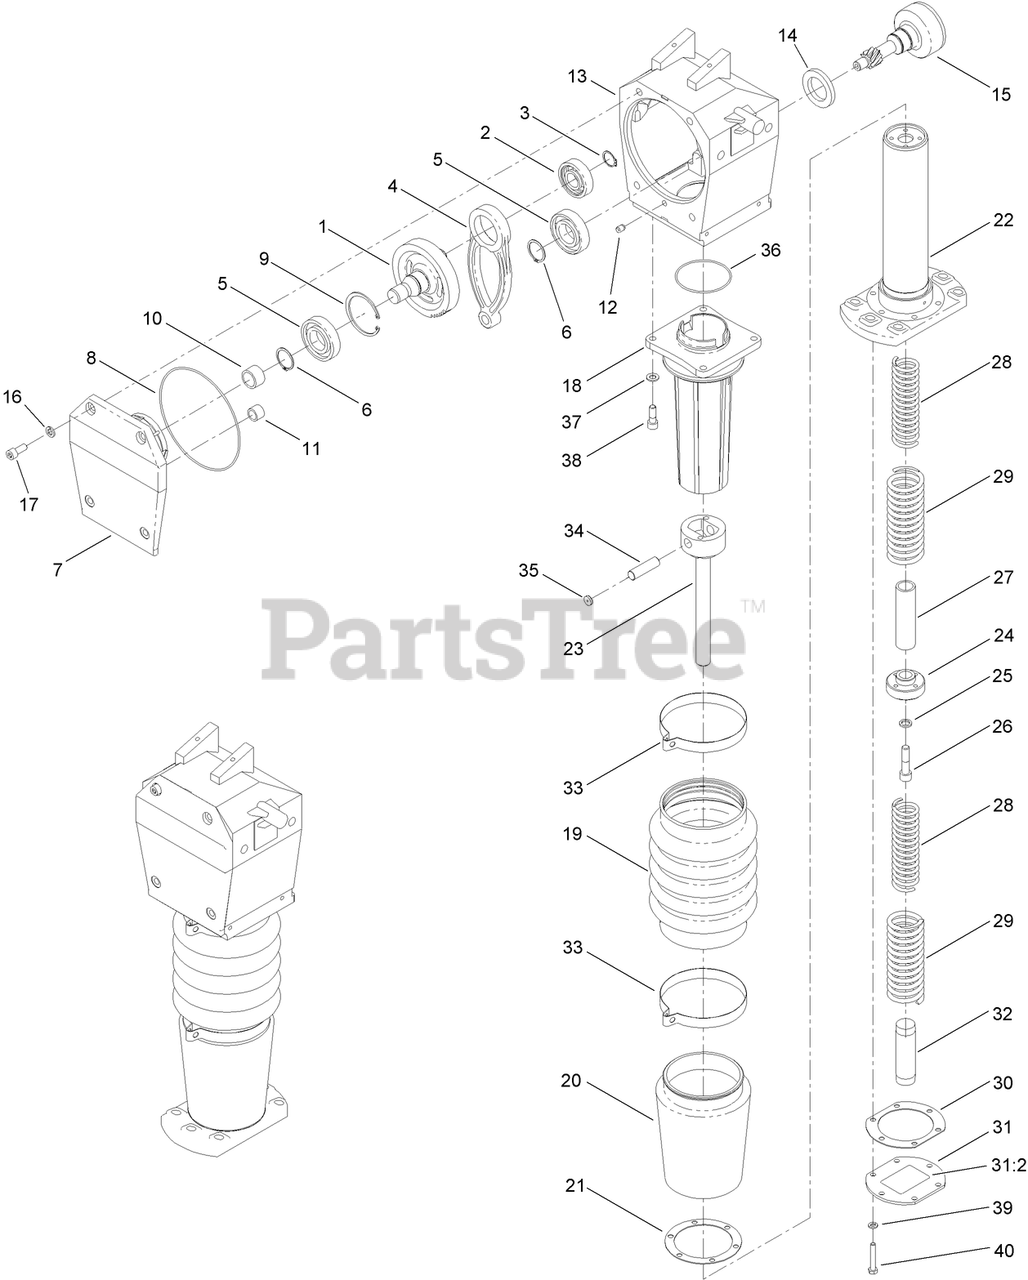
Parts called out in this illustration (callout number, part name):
1	GEAR-HELICAL
2	BEARING-BALL
3	RING-EXTERNAL
4	ROD-CONNECTING
5	BEARING-BALL
6	RING-SNAP, EXTERNAL
7	COVER-FRONT
8	O-RING
9	RING-INTERNAL
10	BEARING-NEEDLE
11	BEARING-NEEDLE
13	GEARCASE
14	SEAL-SHAFT
15	PINION
16	WASHER-LOCK, SPRING
17	SCREW-HSH
18	GUIDE-TUBE
19	BOOT-STOMPER
20	COVER-HOUSING, SPRING
21	GASKET-HOUSING, SPRING COVER
22	HOUSING-SPRING
23	ROD-PISTON
24	PUCK-PISTON
25	WASHER-LOCK
26	SCREW-HSH
27	SNUBBER-SPRING, UPPER
28	SPRING-COMPRESSION, INNER
29	SPRING-COMPRESSION, OUTER
30	GASKET-COVER, SPRING
31	BOTTOM SPRING COVER ASM
31:2	DECAL-WARNING, SPRING
32	SNUBBER-SPRING, LOWER
33	CLAMP-BOOT, STOMPER
35	BUTTON-PIN, CAPTIVATOR
36	O-RING
37	WASHER-FLAT
38	SCREW-HSH
39	WASHER-LOCK
40	Screw-HH
